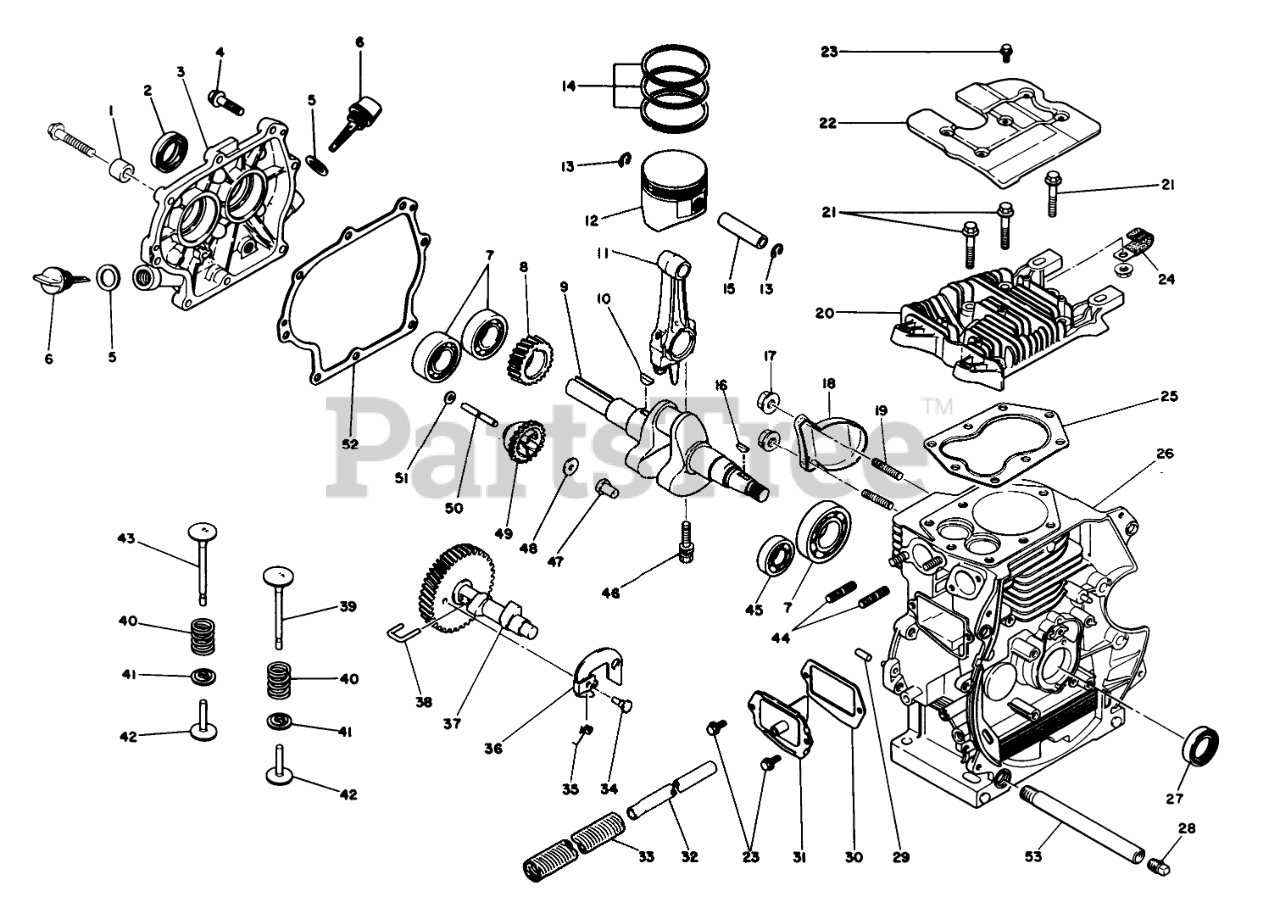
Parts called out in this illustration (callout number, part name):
1	SPACER
2	OIL SEAL
3	CRANKCASE COVER
5	GASKET
6	Gauge-Oil (Incl. Ref. #5)
7	BEARING
8	CRANKSHAFT GEAR
9	CRANKSHAFT
11	Connecting Rod Assembly (Std.)(Incl. Ref. #46)
12	Piston Assembly (Std.)(Incl. Ref. #15)
13	PISTON PIN CLIP
14	PISTON RING SET
15	PISTON PIN
18	COVER
20	CYLINDER HEAD
22	COVER-HEAD
24	CLAMP
25	HEAD GASKET
26	Cylinder Block Assembly (Incl. Ref. #19, 29 & 44)
27	OIL SEAL
28	CAP-PIPE
30	GASKET=BRTHR
31	BREATHER VALVE ASM
32	BREATHER TUBE
35	SPRING
36	FLYWEIGHT
37	Camshaft Assembly (Incl. Ref. #34-36 & 38)
39	INT VALVE
40	VALVE SPRING
41	RETAINER VALVE
42	TAPPET
43	EXHAUST VALVE
45	BEARING
46	CONNECTING ROD BOLT
47	SLIDER-GOV
48	SPACER
49	Governor Gear Assembly (Incl. Ref. #47)
50	SHAFT-GOV.
51	WASHER
52	CRANKCASE GASKET
53	DRAIN TUBE
